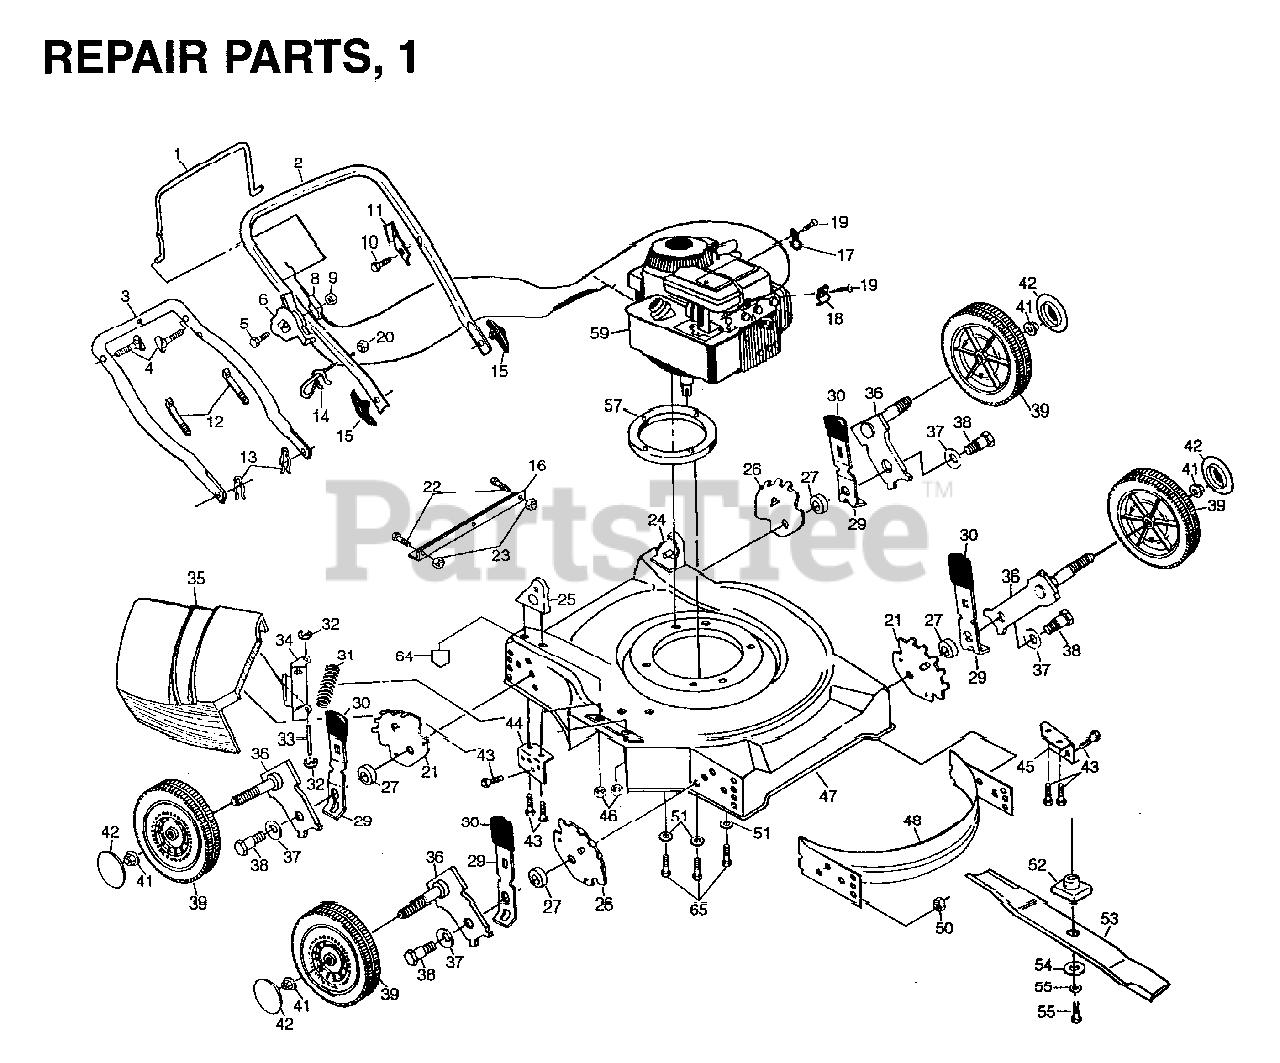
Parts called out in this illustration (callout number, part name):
1	CONTROL BAR/BLACK
2	UPPER HANDLE
4	HANDLE BOLT
5	SCREW 1/4-20 X 2.12
6	THROTTLE CONTROL
8	ENGINE ZONE CONTROL CABLE
9	NUT.CROWNLOCK.1/4
11	BRACKET UPSTOP
12	CLIP CABLE SNAP
13	HAIRPIN COTTER
14	ROPE GUIDE
15	HANDLE KNOB
17	GUIDE CLIP PM
18	WASHER
19	SCREW.HEX.HEAD.WASHER.10-16
20	NUT.CROWNLOCK.1/4
21	BRACKET.WHL.ADJ.L
24	HDLE BRKT ASSY LH
25	HDLE BRKT ASSY RH
26	BRACKET.WHL.ADJ.R
27	RP SPACER HT ADJ
29	SELECTOR SPRING
31	SPRING PM
33	ROD.HINGE.COMBI-C
34	BRACKET PM
36	AXLE, REAR
37	BELLEVILLE WASHER
38	BOLT
39	WHEEL.8X1.75.GREY
41	HEX FLANGE LOCKNT
43	BOLT
46	NUT.CROWNLOCK.1/4
50	LOCKNUT
52	BLADE ADAPTOR
53	BLADE.20.MULCH.(50DK,6020MD)
54	WASHER,HARDEN
55	LOCKWASHER
56	SCREW, HEX HD 3/8-24 X 1-3/8
64	DECAL MOWER CUT/FINGER
